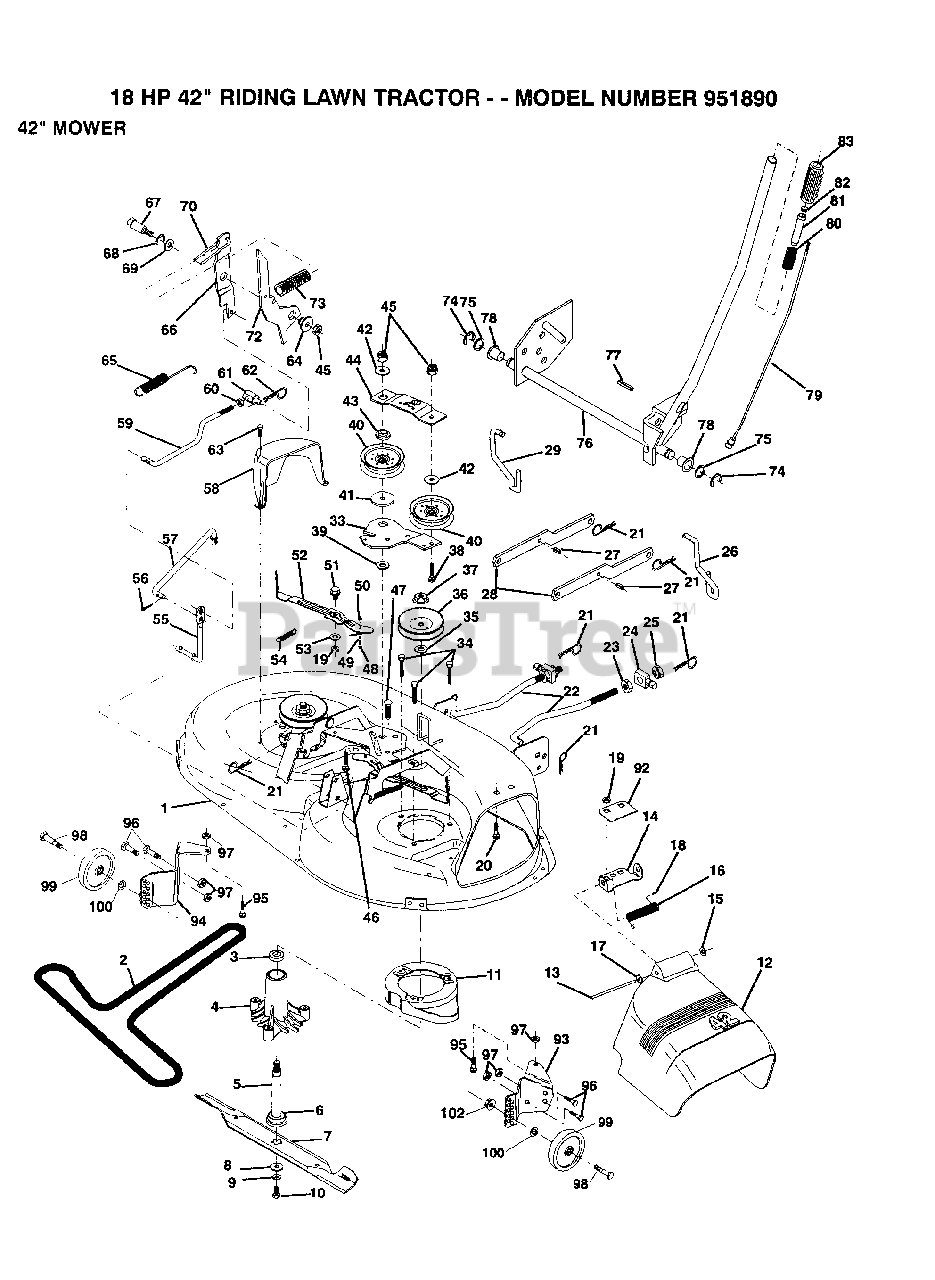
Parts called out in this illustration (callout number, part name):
2	BELT-V.92.4.MWR
3	BEARING
4	HSG ASM MANDREL
6	BEARING.BALL
8	WASHER BLADE
10	BLADE BOLT
12	DEFLECTOR.SHIELD
13	HINGE ROD
14	DEFLECTOR BRKT
15	NUT PUSH M
16	SPRING TORSION
17	WASHER
18	CAP-SLEEVE LT
20	BOLT
22	LINK.FRONT
23	NUT
24	TRUNION
25	NUT.LK.W/WSH.1/2.
26	LIFT LINK RH
27	"PIN,SPRING"
28	SUSP ARM ASM REAR
29	LINK LIFT LH
33	IDLER ARM
35	WASHER
38	BOLT
39	HARDENED WASHER
40	FLAT IDLER PULLEY
41	SPACER RETAINER
42	WASHER GT
43	RETAINER SPACER
44	IDLER ARM STIFF
46	BOLT CARRIAGE
47	XMAS TREE FASTNER
48	SHOULDER BOLT
50	LOCKNUT
52	BRAKE PAD ARM ASM
53	HARD SMALL WASHER
54	SPRING EXTENSION
55	PIVOT ROD
57	CLUTCH ROD SECOND
60	NUT
61	TRUNION
62	RETAINER M
63	SCREW LT
64	BUSHING
65	RETURN SPRING
66	CLUTCH ARM SECOND
67	SHOULDER BOLT
68	RING
69	WASHER
70	SPRING KEEPER
75	WASHER
77	PIN-GROOVE LT
78	NYLON BEARING
83	GRIP
92	STIFFENER BRKT
96	BOLT
99	WHEEL.GAGE.BLK.PL
100	WASHER
102	NUT SPECIAL T
